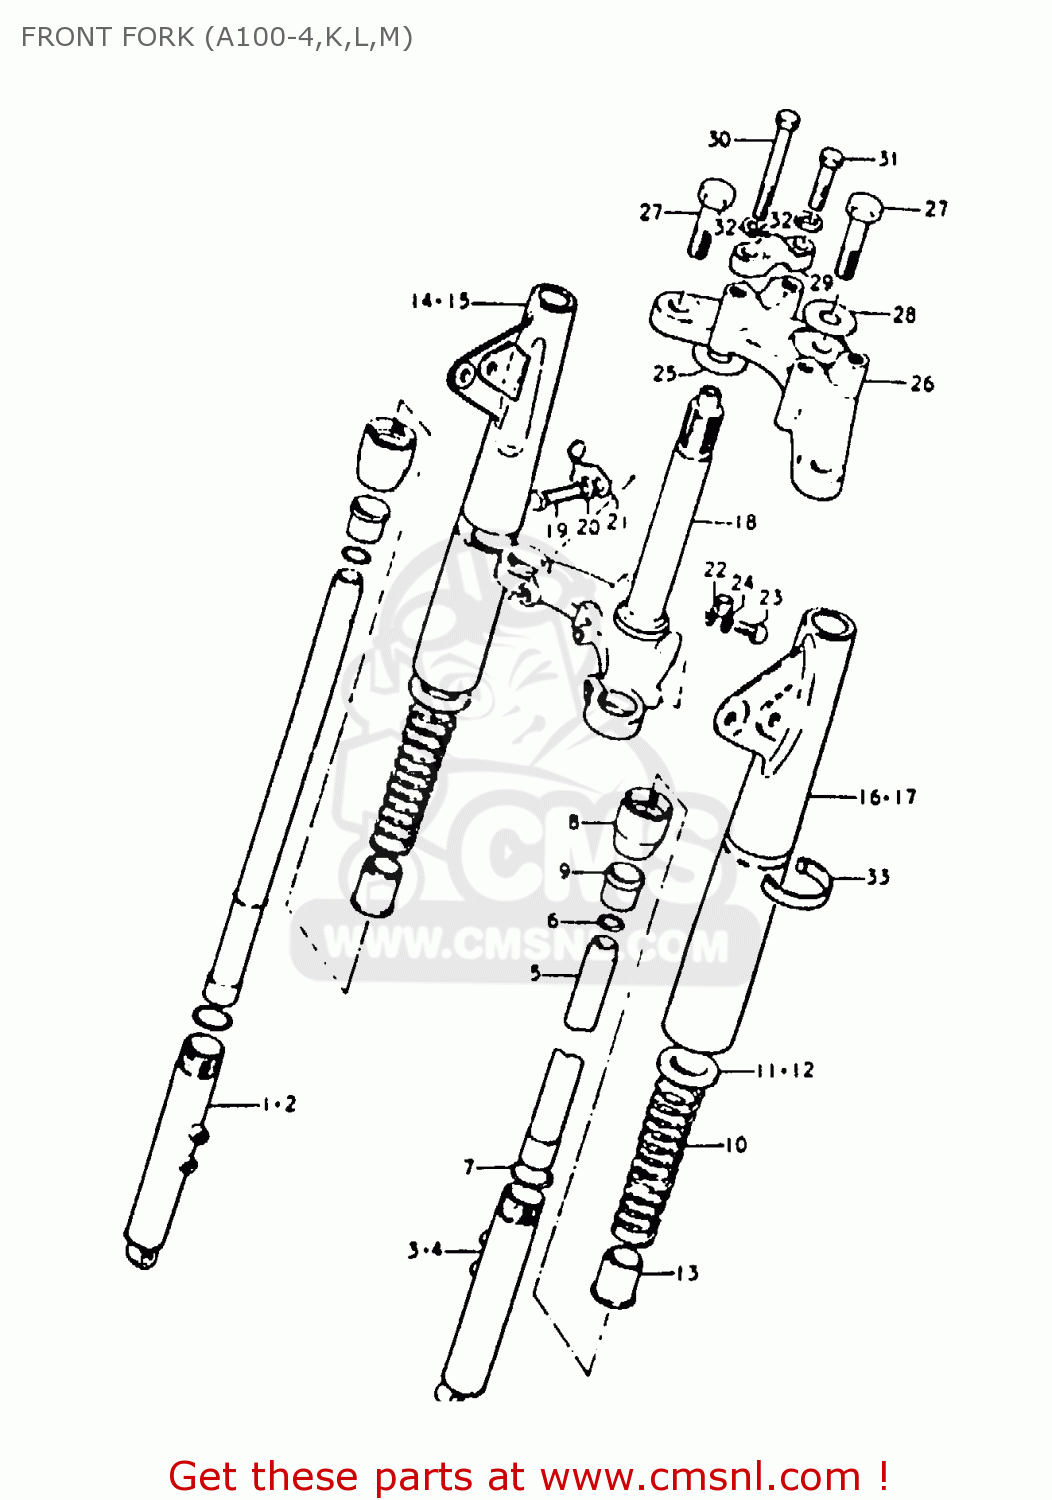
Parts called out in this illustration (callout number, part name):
2	TUBE, OUTER RH
4	TUBE, OUTER LH
5	TUBE,FORK,INNER
6	O RING
7	RING,VALVE STOPPER
8	NUT,FORK OUTER TUBE
9	GUIDE,FORK INNER TUBE
10	SPRING
12	GUIDE,FRONT FORK SPRING C
13	GUIDE,FRONT FORK SPRING
15	COVER, FORK RH
17	COVER, FORK LH
18	STEM,STEERING
19	BOLT,FORK INNER TUBE F
20	LOCK WASHER
21	CLIP,SPEEDOMETER CABLE
22	CLIP,BRAKE CABLE
23	SCREW
24	LOCK WASHER
25	WASHER,STEERING STEM L
26	HEAD,STEERING STEM
27	BOLT,FORK INNER TUBE
28	WASHER
29	HOLDER,HANDLEBAR
30	BOLT
31	BOLT
32	LOCK WASHER
33	COVER, SPRING
